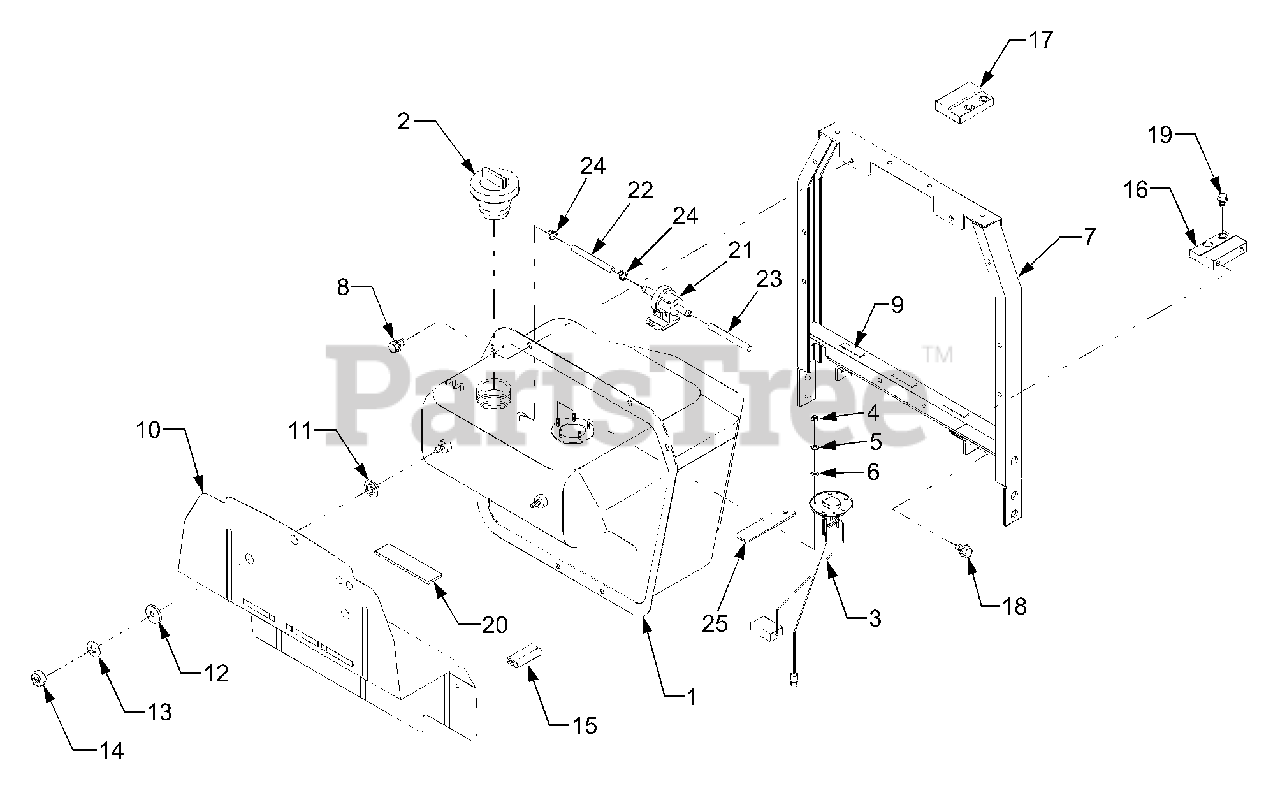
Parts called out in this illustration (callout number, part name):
2	Fuel Cap Assy
3	Fuel Sender Ass'y
5	Washer, Spring
6	Washer, Plain
7	Bracket, Bonnet
9	Rubber, Cushion
10	Plate, Shuttle
13	Washer, Plain
20	Rubber, Cushion
25	Bracket (Fuel Filter)
